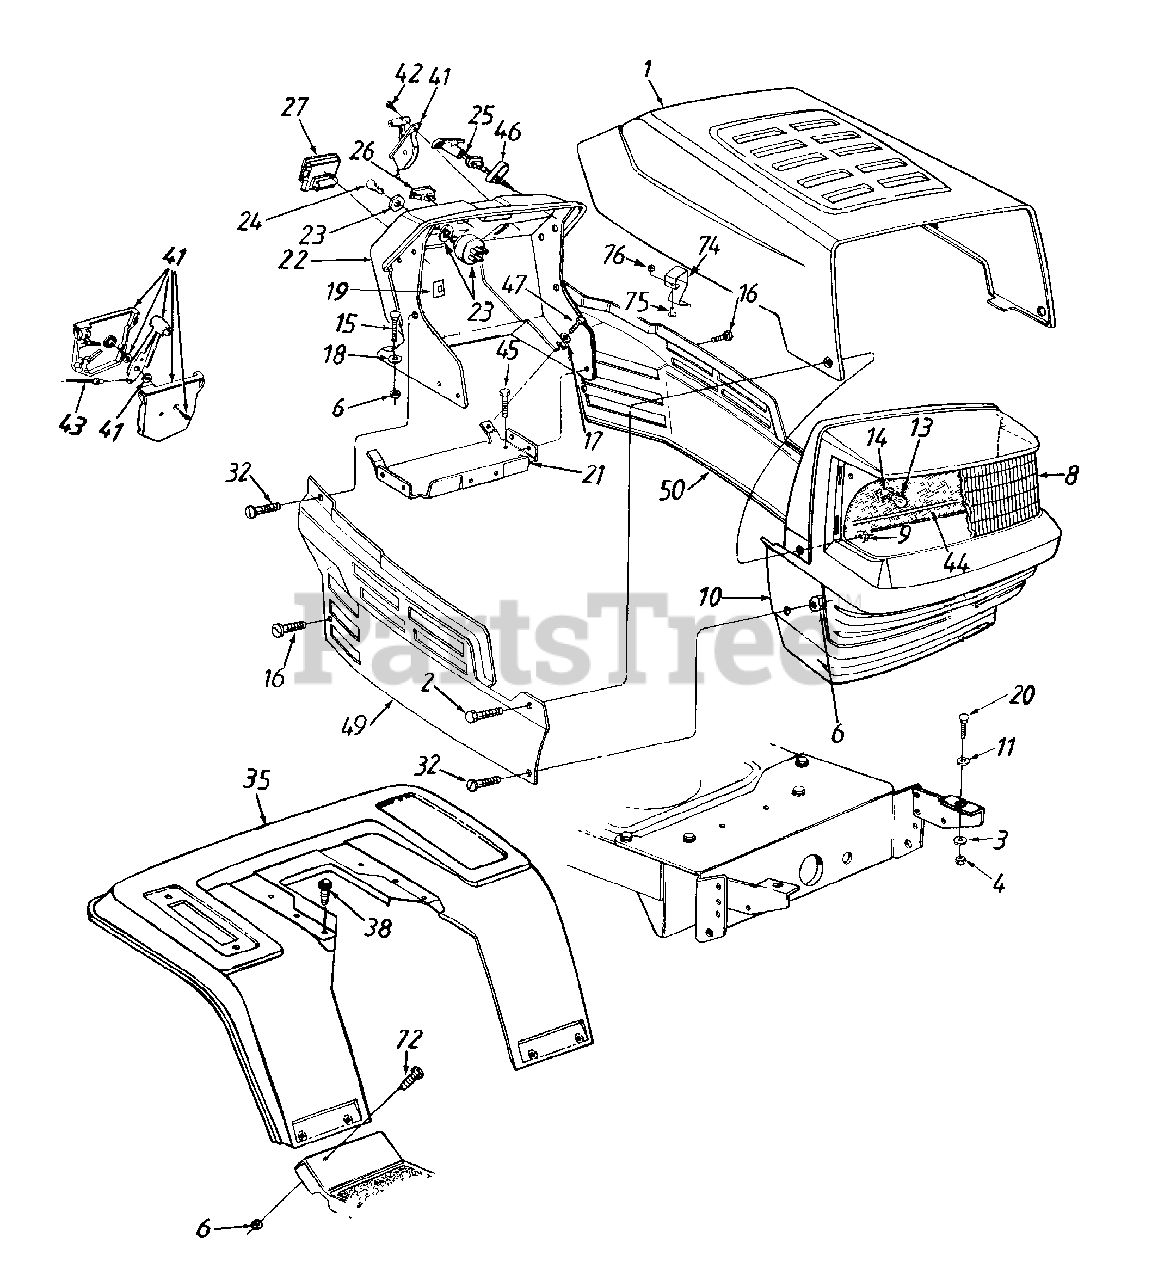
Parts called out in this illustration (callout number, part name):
3	Lock Washer 5/16" I.D.
4	Hex Nut 5/16-18 Thd.
6	Hex Sems Nut 1/4-20 Thd.
8	Headlight Lens w/o Logo
9	Flange Lock Nut 1/4-20 Thd.
10	Grille
11	Flat Washer .344" I.D. x 1" O.D.
13	Lamp
14	Socket
15	Carriage Bolt 1/4-20 x .75" Lg.
16	Hex Wash. Hd. TT-Tap Scr .1/4-20 x .5".
17	Flat Washer .281" I.D. x .73" O.D.
18	Bolt Retainer 1/4" I.D.
19	Speed Nut 1/4-20 Thd.
20	Hex Bolt 5/16-18 x .75"
23	Ignition Switch
24	Ignition Key
25	Choke Control 23" Lg.
26	Light Switch
27	Ammeter
32	Pan Hd. Scr. 1/4-20 x .75"
41	Throttle Box Assembly
42	Truss Mach. AB-Tap Scr.#10 x .5" Lg.
43	Throttle Control Wire 18.5" Lg.
44	Grille Reflector Label
45	Hex Wash. Hd. B-Tap Scr. 5/16-18 x .5"
46	Choke Retainer
47	Hex TT-Tap Scr. 1/4-20 x .75" Lg.
74	Hood Latch
75	Hex Sems Nut 10-24 Thd.
76	Truss Mach. Scr. 10-24 x .5" Lg.
